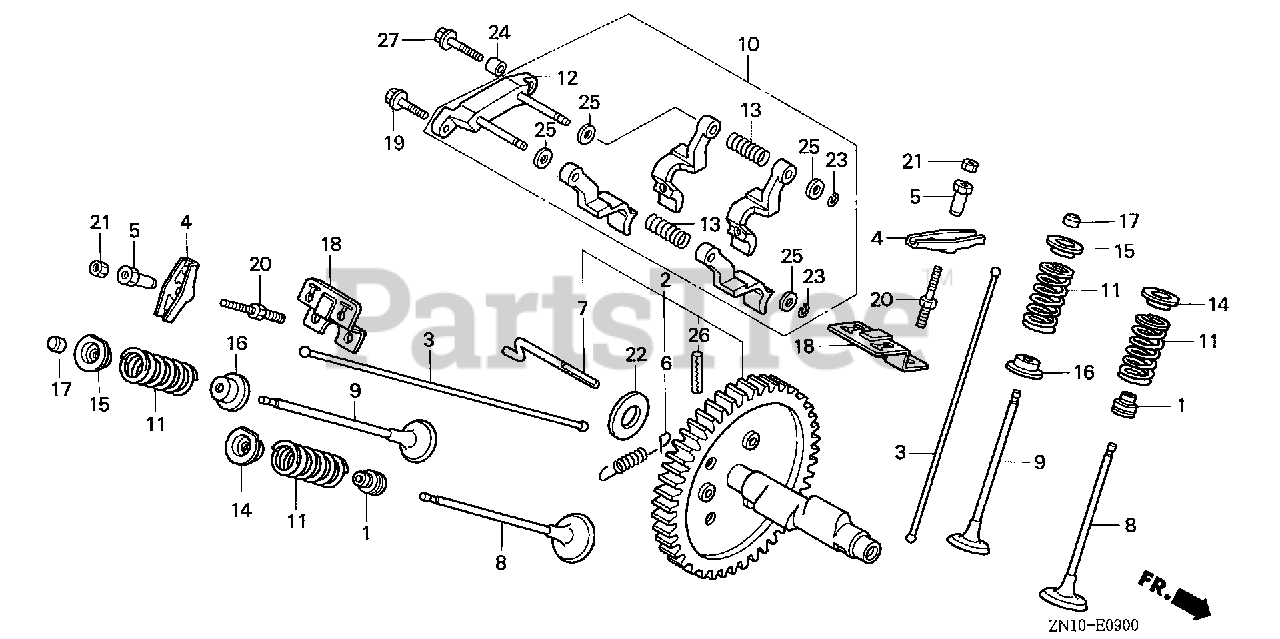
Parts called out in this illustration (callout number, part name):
1	SEAL, VALVE STEM
2	CAMSHAFT ASSY.
3	ROD, PUSH
4	ARM, VALVE ROCKER
5	PIVOT, ROCKER ARM
6	SPRING, WEIGHT RETURN
7	PIN, DECOMPRESSION
8	VALVE, IN. (GAS)
9	VALVE, EX. (GAS)
10	LIFTER ASSY., VALVE
11	SPRING, VALVE
12	SHAFT, VALVE LIFTER
13	SPRING, VALVE LIFTER
14	RETAINER, IN. VALVE SPRING (EXHAUST SIDE)
15	RETAINER, IN. VALVE SPRING (EXHAUST SIDE)
16	SEAT, VALVE SPRING
18	PLATE, PUSH ROD GUIDE
19	BOLT, FLANGE (5X16)
20	BOLT, PIVOT (8MM)
21	NUT, PIVOT ADJ.
22	WASHER, THRUST (17.2MM)
23	CLIP, GOVERNOR HOLDER
24	PIN A, DOWEL (8X12)
25	WASHER, PLAIN (6MM)
26	PIN, SPRING (6X28)
27	BOLT, FLANGE (6X25)
